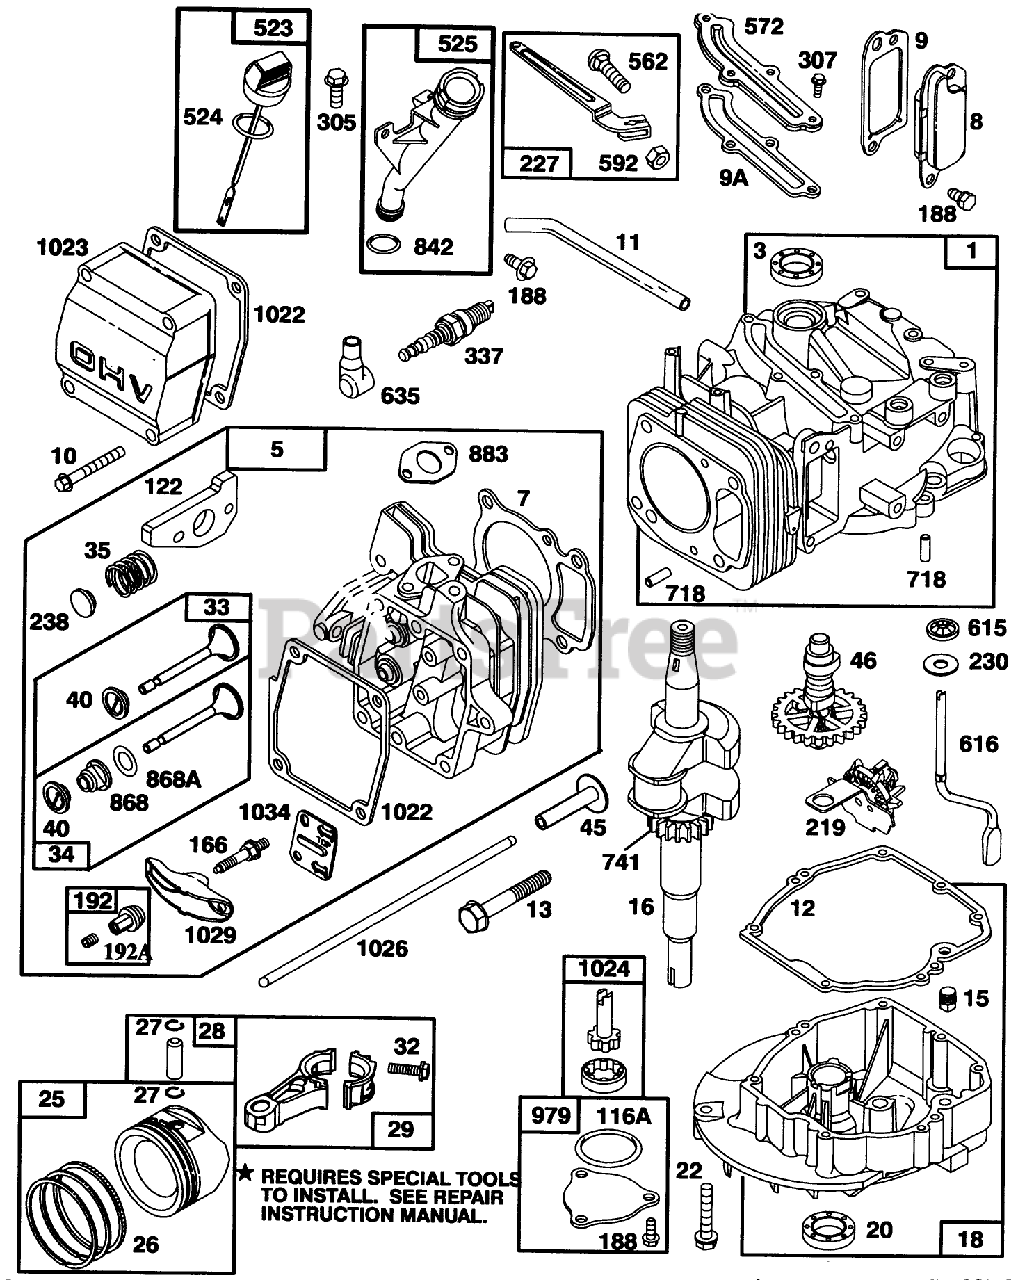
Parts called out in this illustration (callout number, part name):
104	FLOAT HINGE PIN
116	SEALING GASKET
118	VALVE KIT - NEEDLE
121	CARBURATOR OVERHAUL KIT
122	ADAPTER ASSEMBLY
134	Valve-Float (Includes Seat)
137	FLOAT BOWL GASKET
358	GASKET SET
634	SEAL WASHER
977	CARBURATOR GASKET SET
1039	FLOAT LIMITER
